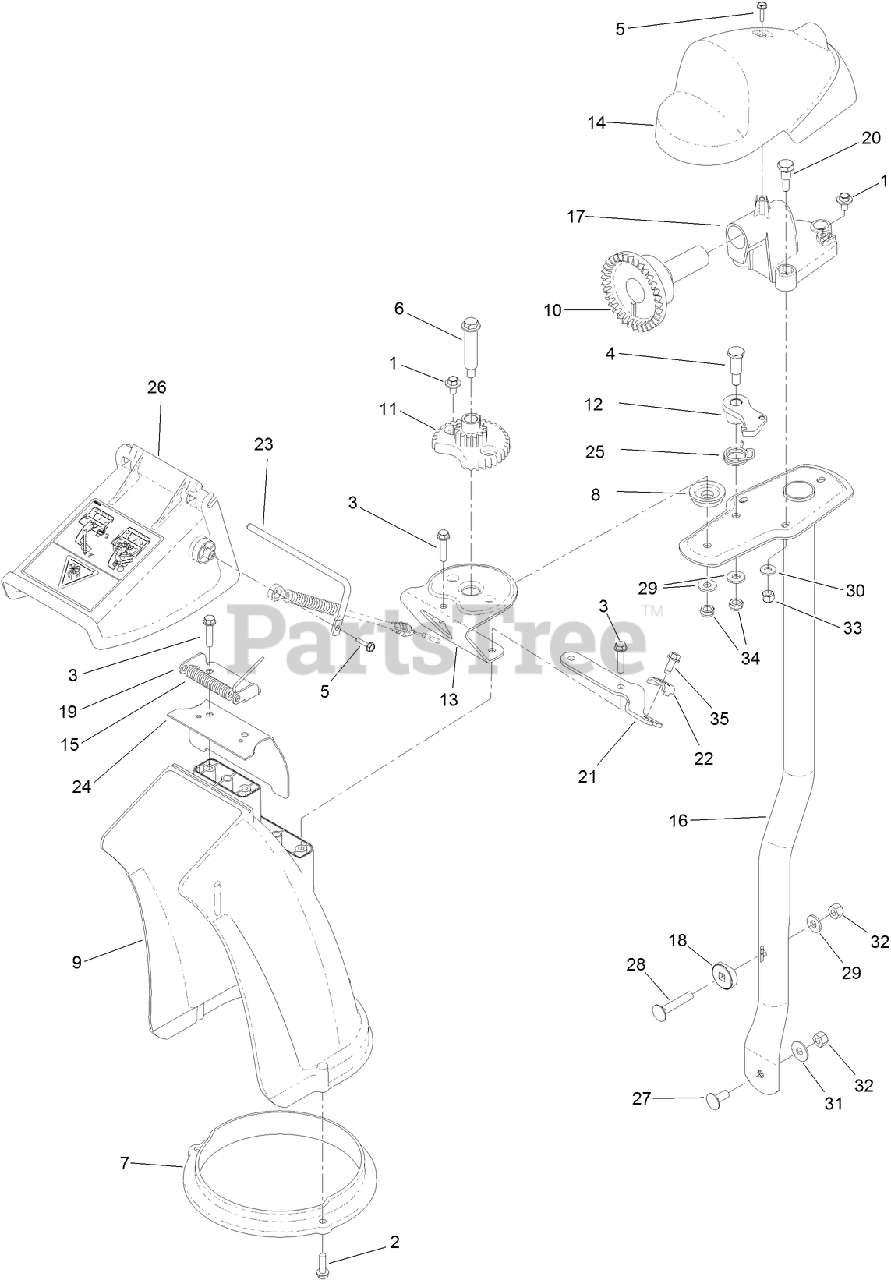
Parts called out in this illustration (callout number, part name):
1	SCREW AND WASHER ASM
2	SCREW-PLASTITE, HWH
3	SCREW-PLASTITE, HWH
4	SCREW-SHOULDER, HH
5	SCREW-PLASTITE, HWH
6	BOLT-SHOULDER
7	RING-CHUTE
8	SPACER-CHUTE
9	CHUTE-DISCHARGE
10	GEAR-FACE
11	GEAR-CHUTE
12	LATCH-CHUTE
13	BRACKET-SUPPORT, CHUTE
14	COVER-GEAR, CHUTE
15	SPRING-TORSION
16	TUBE-SUPPORT
17	MOUNT-GEAR, FACE
18	WASHER-CURVED
19	BRACKET-DEFLECTOR
20	SCREW-SHOULDER
21	BRACKET-CLAMP, CABLE
22	CLAMP-CABLE
23	ROD-DEFLECTOR
24	SEAL-CHUTE
25	SPRING-TORSION
26	DEFLECTOR-CHUTE, CE
27	BOLT-CARR
28	BOLT-CAR
29	WASHER-FLAT
30	WASHER-FLAT
31	WASHER-BELLEVILLE
32	NUT-HEX
33	NUT-HEX
34	NUT-HEX
35	SCREW-HWH
